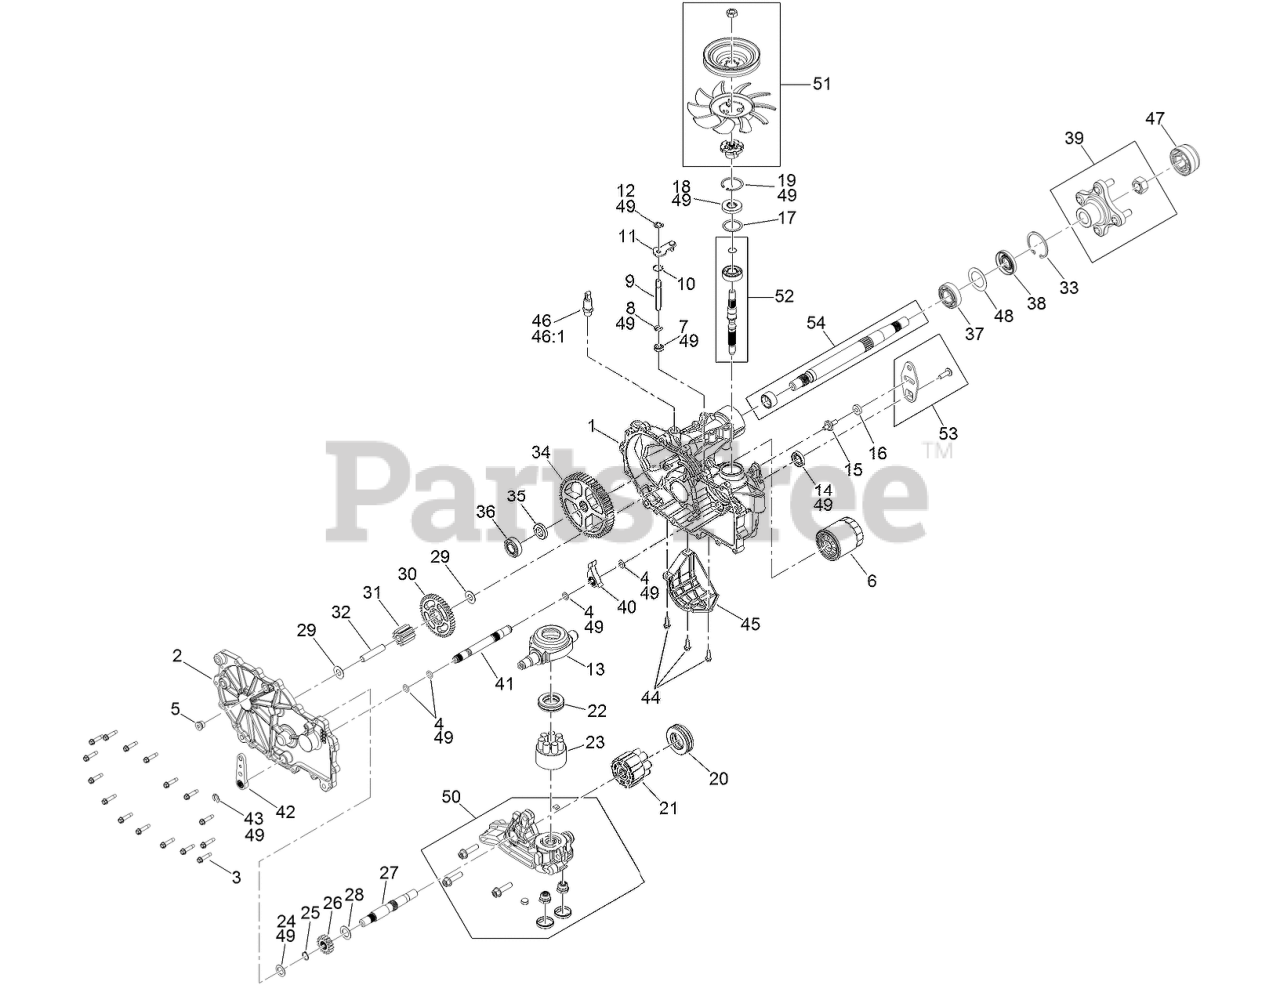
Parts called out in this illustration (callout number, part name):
1	MAIN HOUSING KIT
2	LH SIDE COVER KIT
3	SCREW-HHF
4	O-RING
5	PLUG-THREAD, STRAIGHT
6	ELEMENT-OIL FILTER, HYD
7	SEAL-LIP
8	RING-RETAINING, EXTERNAL
9	ROD-BYPASS
10	RING-RETAINING, INTERNAL
11	ARM-BYPASS
12	RING-RETAINING, EXTERNAL
13	SWASHPLATE-TRUNNION
14	SEAL-LIP
16	PUCK-FRICTION
17	SPACER
18	SEAL-LIP
19	RING-RETAINING
20	BEARING-THRUST
21	MOTOR CYLINDER BLOCK KIT
22	BEARING-THRUST
23	PUMP BLOCK ASM
24	WASHER-FLAT
25	RING-RETAINING
26	GEAR-16T
27	SHAFT-MOTOR
28	WASHER
29	WASHER
30	GEAR-43T
31	GEAR-11T
32	PIN-JACKSHAFT
33	RING-RETAINING
34	GEAR-54T
35	SPACER
36	BEARING-BALL
37	BEARING-BALL
39	HUB KIT
40	PAWL-BRAKE
41	SHAFT-BRAKE, INBOARD
42	HANDLE-BRAKE
43	RING-RETAINING, EXT
45	GUARD-FILTER, LH
46	ADAPTER-STRAIGHT
46:1	O-RING
47	COVER-NUT, AXLE
48	SPACER
49	SEAL KIT
50	CENTER SECTION KIT
51	FAN PULLEY KIT
52	INPUT SHAFT KIT
53	CONTROL ARM KIT
54	AXLE SHAFT KIT
